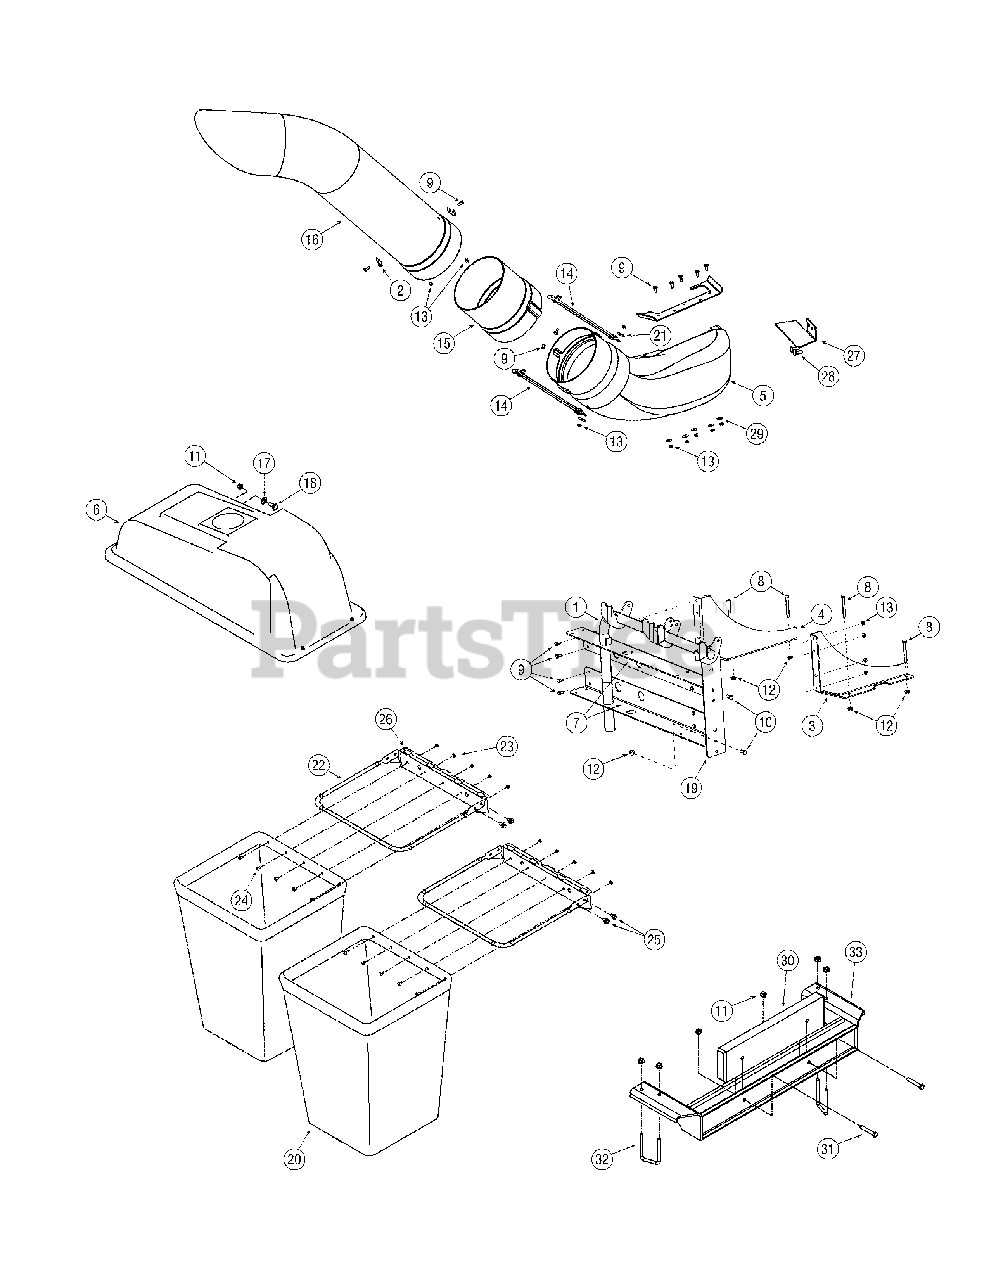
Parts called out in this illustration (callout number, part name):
1	Support Assem. Catcher Cover
2	Retainer Hook Bracket
3	Mounting Assembly: RH
4	Mounting Assembly: LH
5	Elbow Chute Assembly
6	Grass Catcher Cover
7	Hanger Bracket
8	Hex Bolt 5/16-18 x 2.75"
9	Hex Bolt 1/4-20 x .620"
10	Hex Bolt 5/16-18 x .75"
11	Flange Lock Nut 3/8-16
12	Flange Lock Nut 5/16-18
13	Hex Flange Lock Nut 1/4-20
14	Retainer Strap Assembly
15	8" Extension Chute
16	8" Catcher Tube
17	Belleville Washer
18	Shoulder Screw 3/8-16
19	Support Bracket
20	Grass Bag
21	Flat Washer
22	Grassbag Frame
25	Machine Screw
26	Bag Frame Hangar Bracket
28	Carriage Bolt 3/8-16
29	Bell Washer
31	Hex Head Screw 3/8-16
32	U-bolt 3/8-16
33	Weight Bar Assembly Bracket
